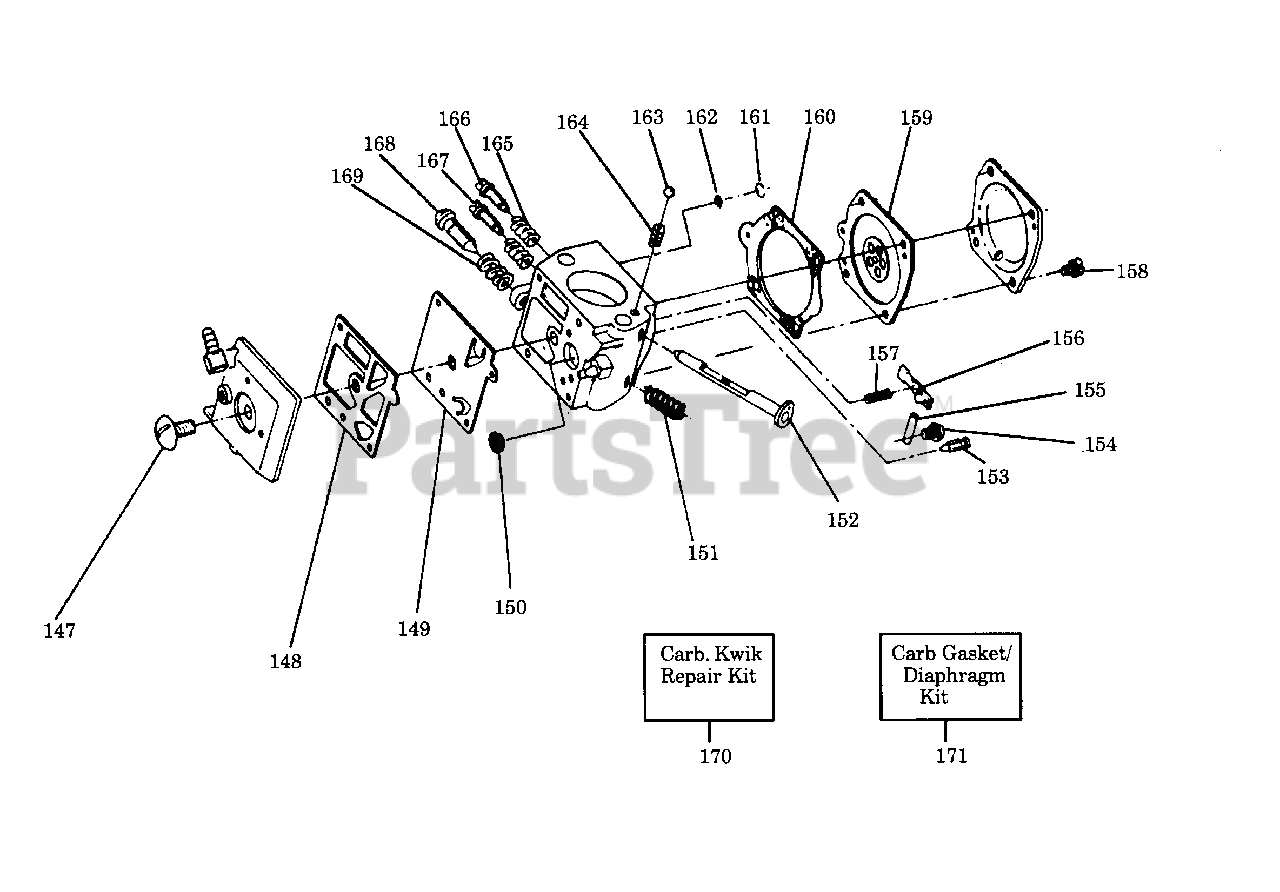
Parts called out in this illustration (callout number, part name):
148	Fuel Pump Gasket
149	Fuel Pump Diaphragm
150	Inlet Screen
151	Throttle Spring
152	Choke Shaft & Lever Ass'y
153	Inlet Needle Valve
154	Screw
155	Pin
156	Metering Lever
157	Spring
159	Metering Diaphragm
160	Metering Diaphragm Gasket
161	Retaining Ring
162	Check Valve Screen
164	Spring
165	Needle Adjusting Spring
166	High Speed Needle
167	Idle Needle
168	Idle Adjust Screw
169	Idle Adjust Spring
170	Kwik Repair Kit
171	Carb. Gasket Kit
